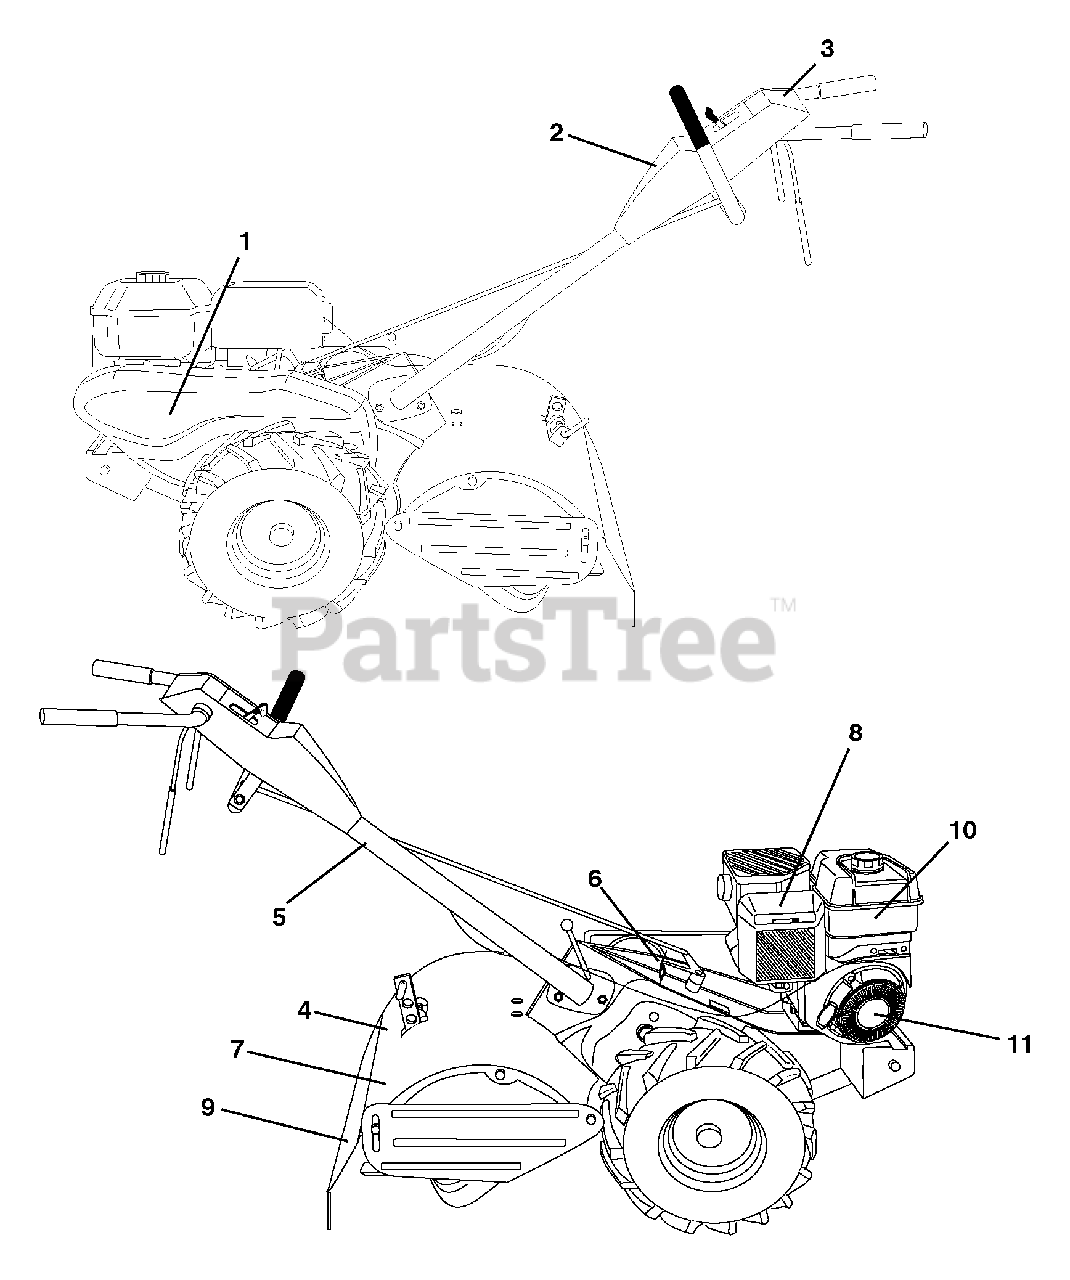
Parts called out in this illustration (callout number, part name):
1	Decal, Husqvarna, Belt Guard
2	Decal, Husqvarna, Control Panel
3	Decal, Tine Control
4	Decal, Tine Shield
5	Decal, Hand Placement
6	Decal, Shift Indicator
7	Decal, Warning
8	Decal, Engine, 8.75
9	Decal, Warning, Rotating Tines
10	Decal, Engine, Fuel Tank, 8.75
11	Decal, Rewind Starter, B&S
